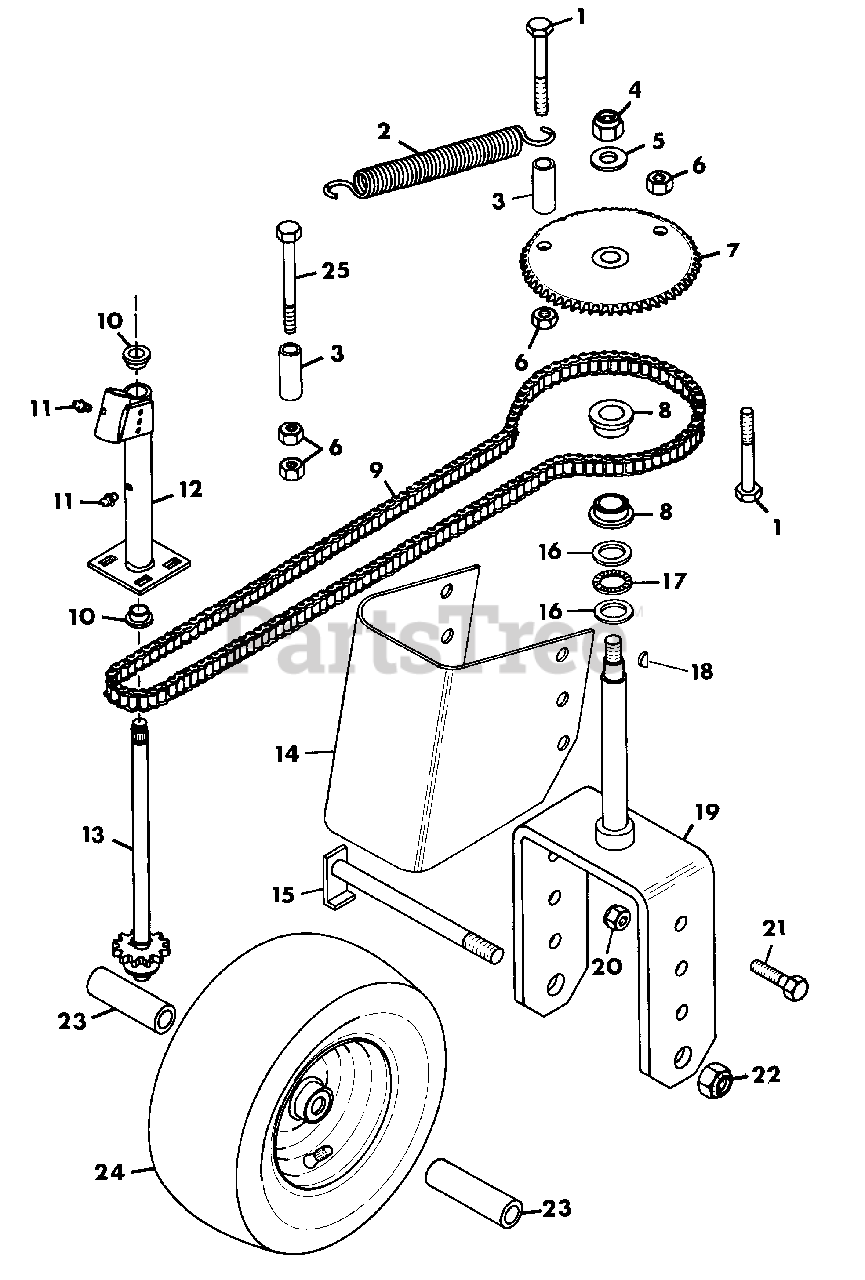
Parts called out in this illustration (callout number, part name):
1	BOLT, HEX 1/2-13X3.25
2	SPRING
3	BUSHING, MOWER PIVOT
4	NUT, LOCK 7/8-9
5	WASHER, FLAT .969X2.250X.165
6	NUT, HEX 1/2-13
7	SPROCKET, 60T #40
8	BEARING, FLANGED
9	CHAIN, OFC
10	BEARING, FLANGED
11	FITTING, LUBE 1/4-28
12	TUBE, STEERING
13	WELDMENT, STEERING SHAFT
14	SHIELD, GRASS
15	AXLE
16	BEARING, THRUST RACE
17	BEARING, NEEDLE THRUST
18	KEY, WOODRUFF .250X.875 HARD #A
19	WELDMENT, WHEEL FORK
20	NUT, LOCK 1/2-13
21	BOLT, HEX 1/2-13X1.25
22	NUT, LOCK 3/4-16
23	SPACER, WHEEL
24	WHEEL, REAR
25	BOLT, HEX 1/2-13X3.75
